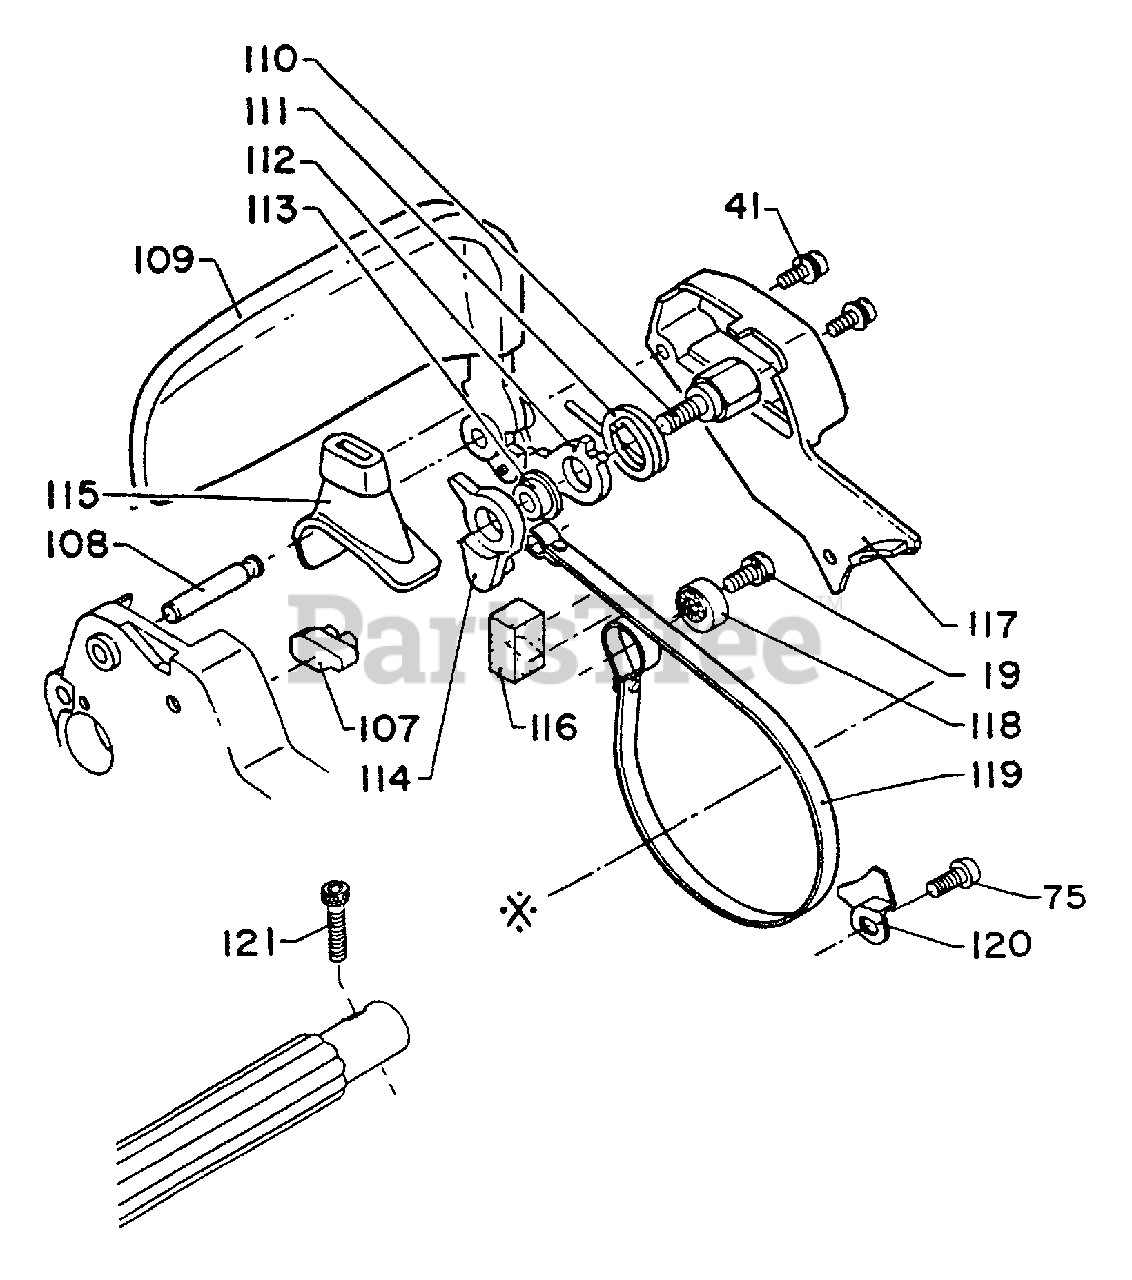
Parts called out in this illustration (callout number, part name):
19	SCREW 5×10
41	SCREW 4×10
75	SCREW 5×10
107	RESET, BRAKE
109	HANDLE, BRAKE
111	SPRING, RETURN
114	CONNECTOR
115	COVER, BRAKE
116	SEAL
117	COVER, BRAKE
118	ADJUSTER, BRAKE BAND
119	BAND, BRAKE
120	RETAINER, BRAKE BAND
121	BOLT 5×25
